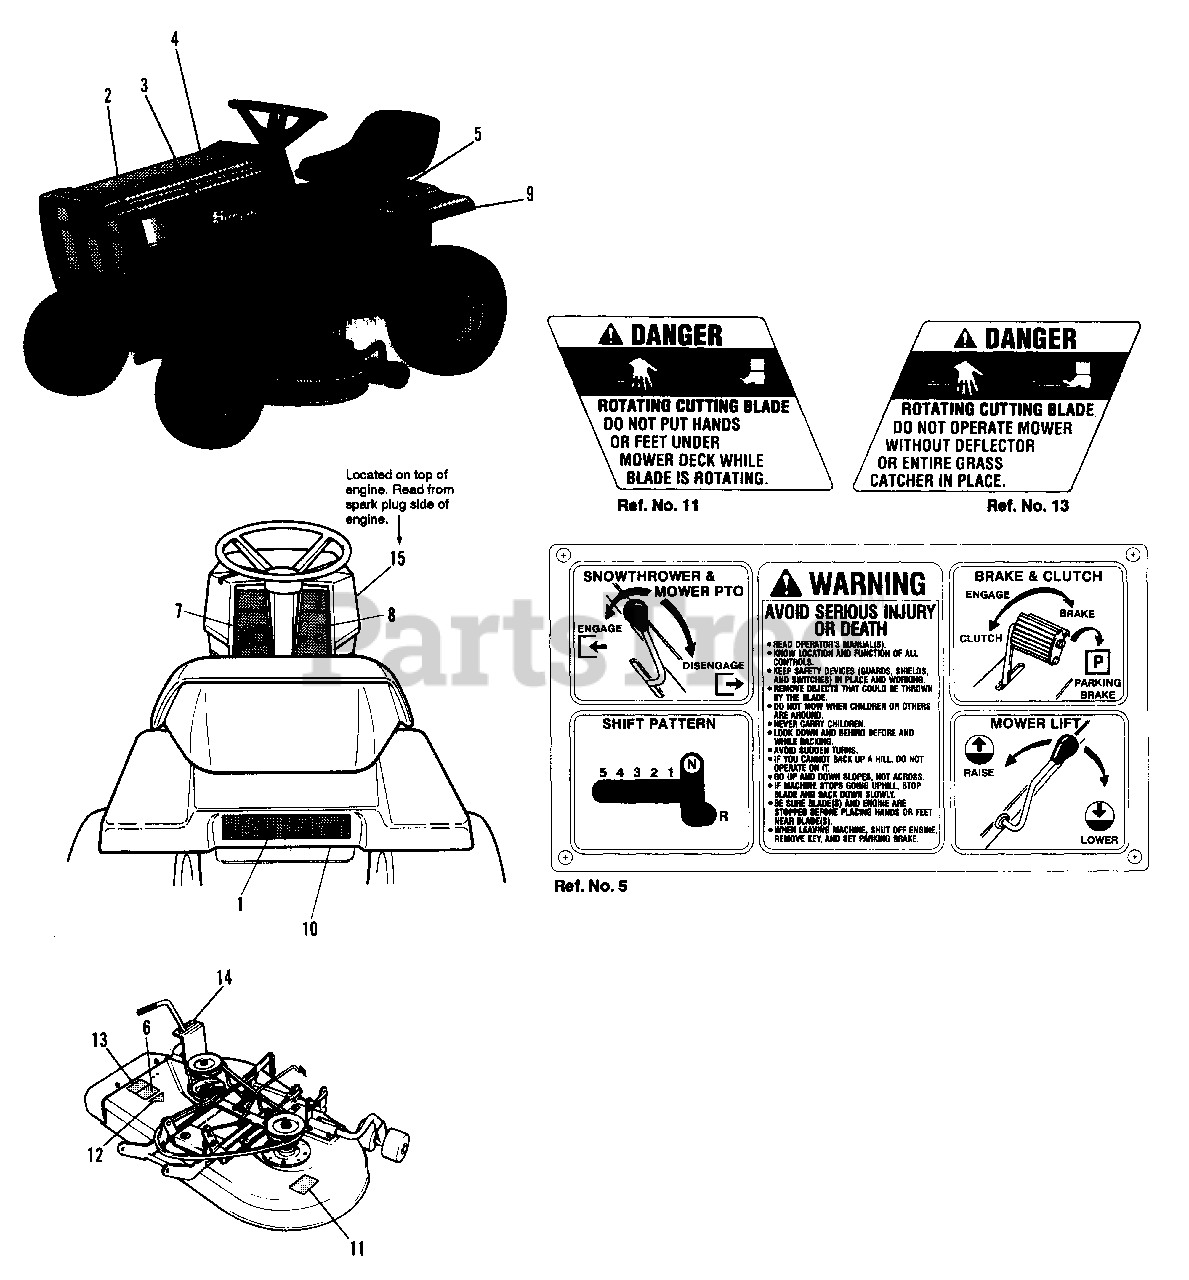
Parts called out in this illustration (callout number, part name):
1	DECAL, Simplicity
2	DECAL, Hood, R.H.
3	DECAL, Hood, L.H.
4	DECAL, Drive Belt
5	DECAL, Shift Pattern
6	DECAL, Cutting Width, 36"
7	DECAL, Dash, L.H. Side
8	DECAL, Dash, R.H. Side
9	DECAL, 12LTG
10	DECAL, Battery
11	DECAL, Danger, Rotating Blade
12	DECAL, OPEI
13	DECAL, Danger, Deflector in Place
14	DECAL, Mower Height
15	DECAL, Simplicity, 12 HP, I/C
